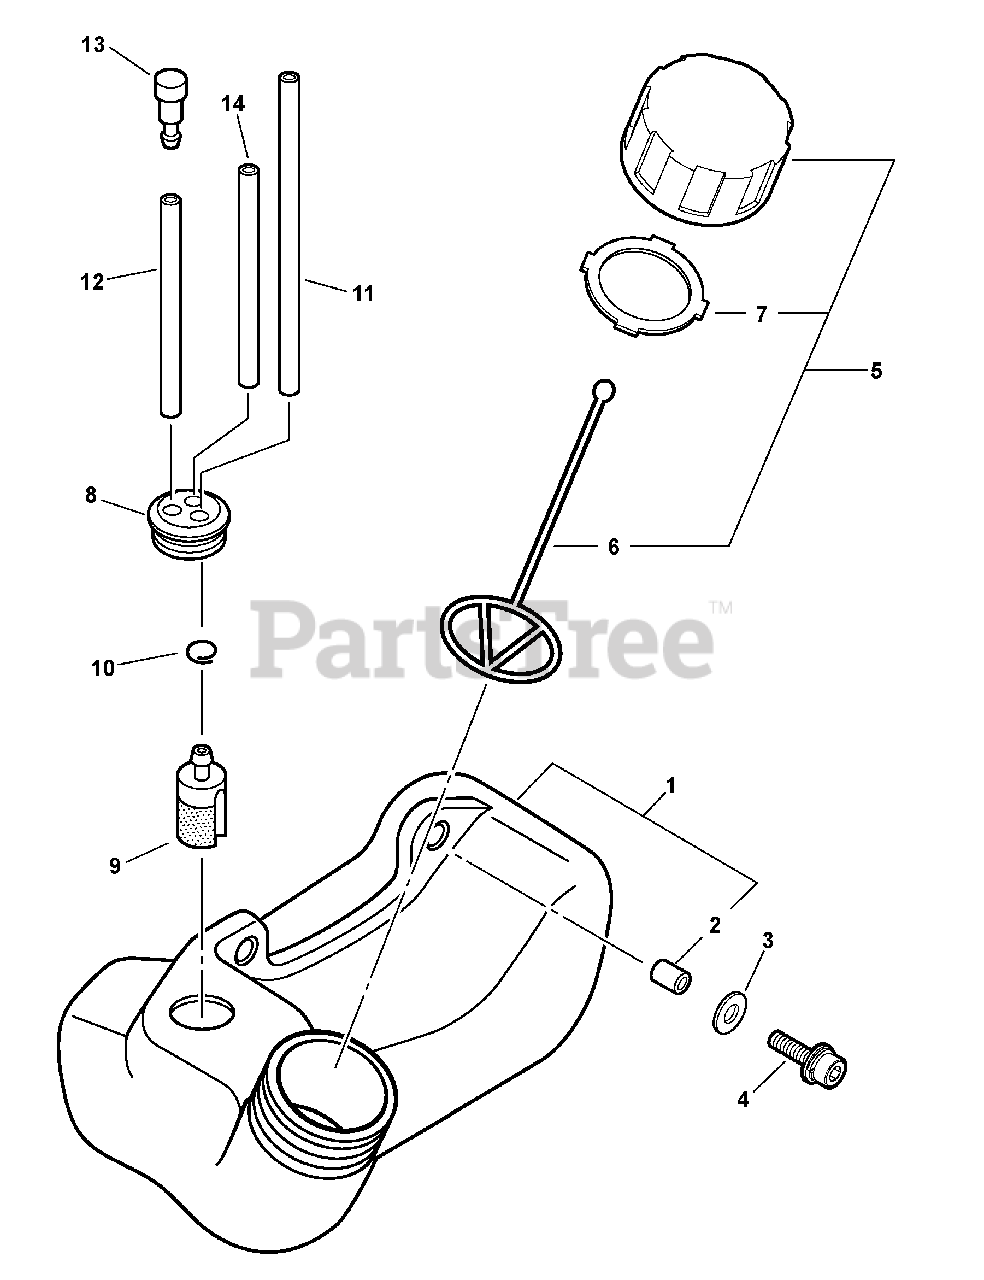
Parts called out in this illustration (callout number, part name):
1	TANK, FUEL
2	SPACER 6.2×7.8×6
3	WASHER 5.5×12×0.8
4	BOLT 5×16
5	CAP ASSY, FUEL
6	CONNECTOR, CAP L= 100 MM
7	GASKET, FUEL CAP
8	GROMMET, FUEL
9	FILTER, FUEL
10	CLIP 6 MM
11	PIPE, FUEL 3x-5x-180
12	PIPE, FUEL 3x-5x-70 BLACK
13	VENT ASSY
14	PIPE, FUEL 3×6×80 CLEAR
